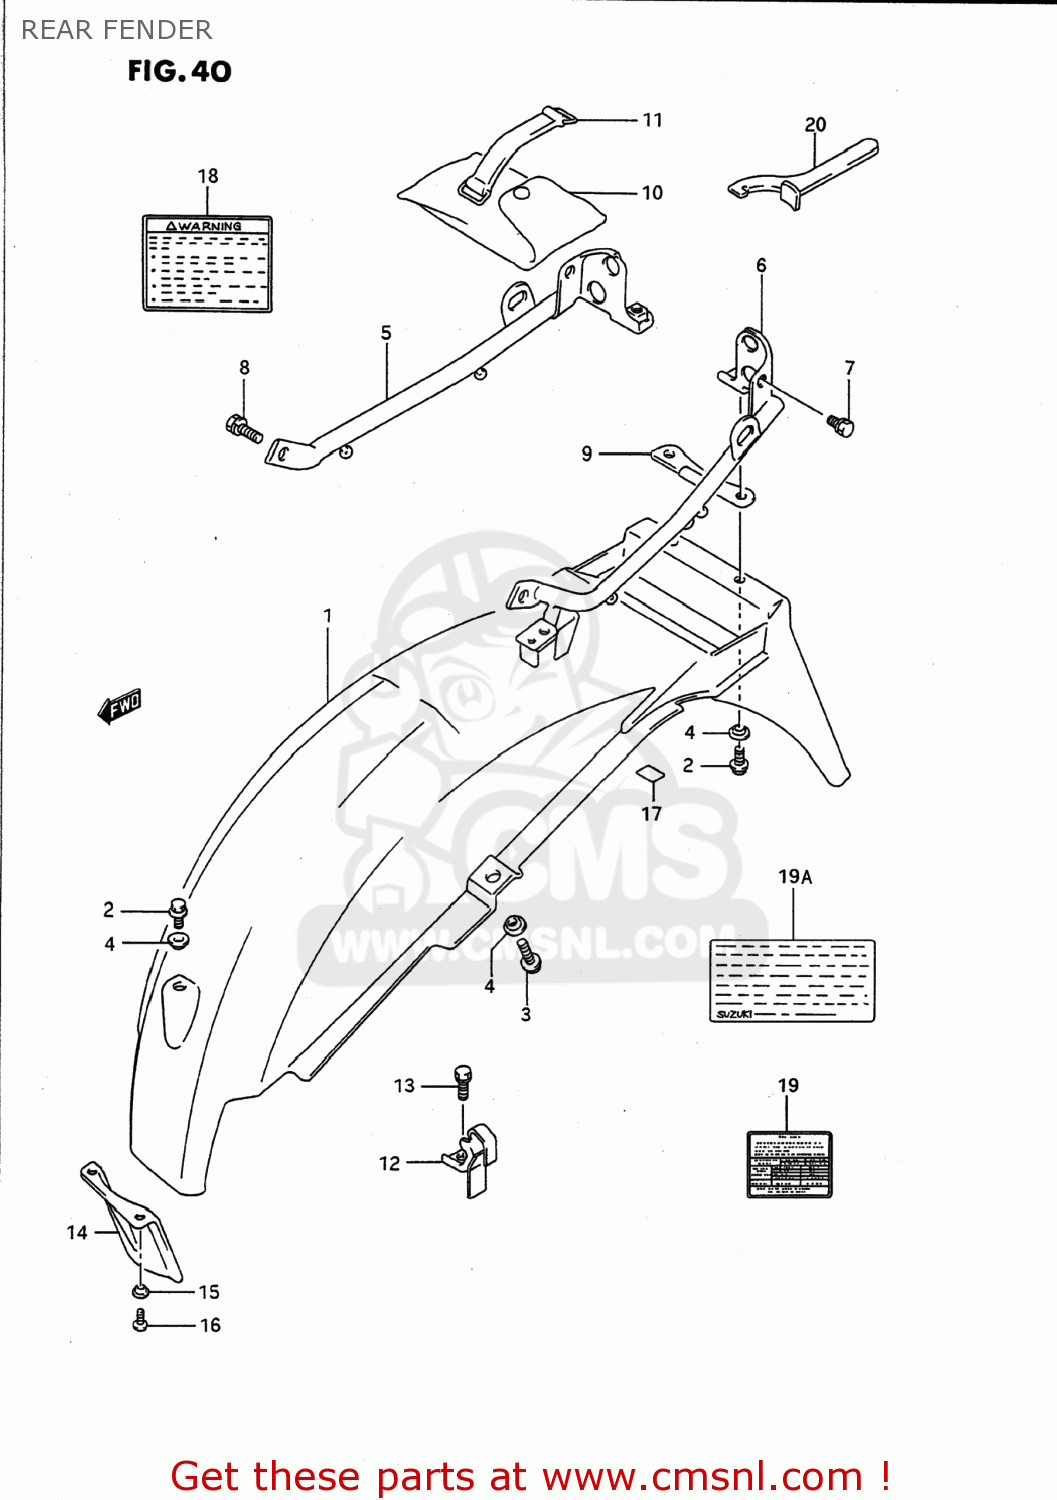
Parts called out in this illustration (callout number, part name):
1	BODY,REAR FENDER
2	BOLT
3	BOLT
4	WASHER
5	BRACE,REAR FENDER
6	BRACE,REAR FENDER
7	BOLT
8	BOLT
9	PLATE,TOOL HOLDER
10	TOOL ASSY
11	BAND
12	HOLDER,HELMET
13	BOLT
14	GUARD,RR UNIT MUD
15	WASHER
16	SCREW
17	TAPE,RR FENDER
18	LABEL
19	LABEL,TIRE AIR PRESSURE
19A	LABEL
20	CLAMP
21	LABEL (VACUUM HOSE ROUTING)
22	MANUAL, OWNER'S
